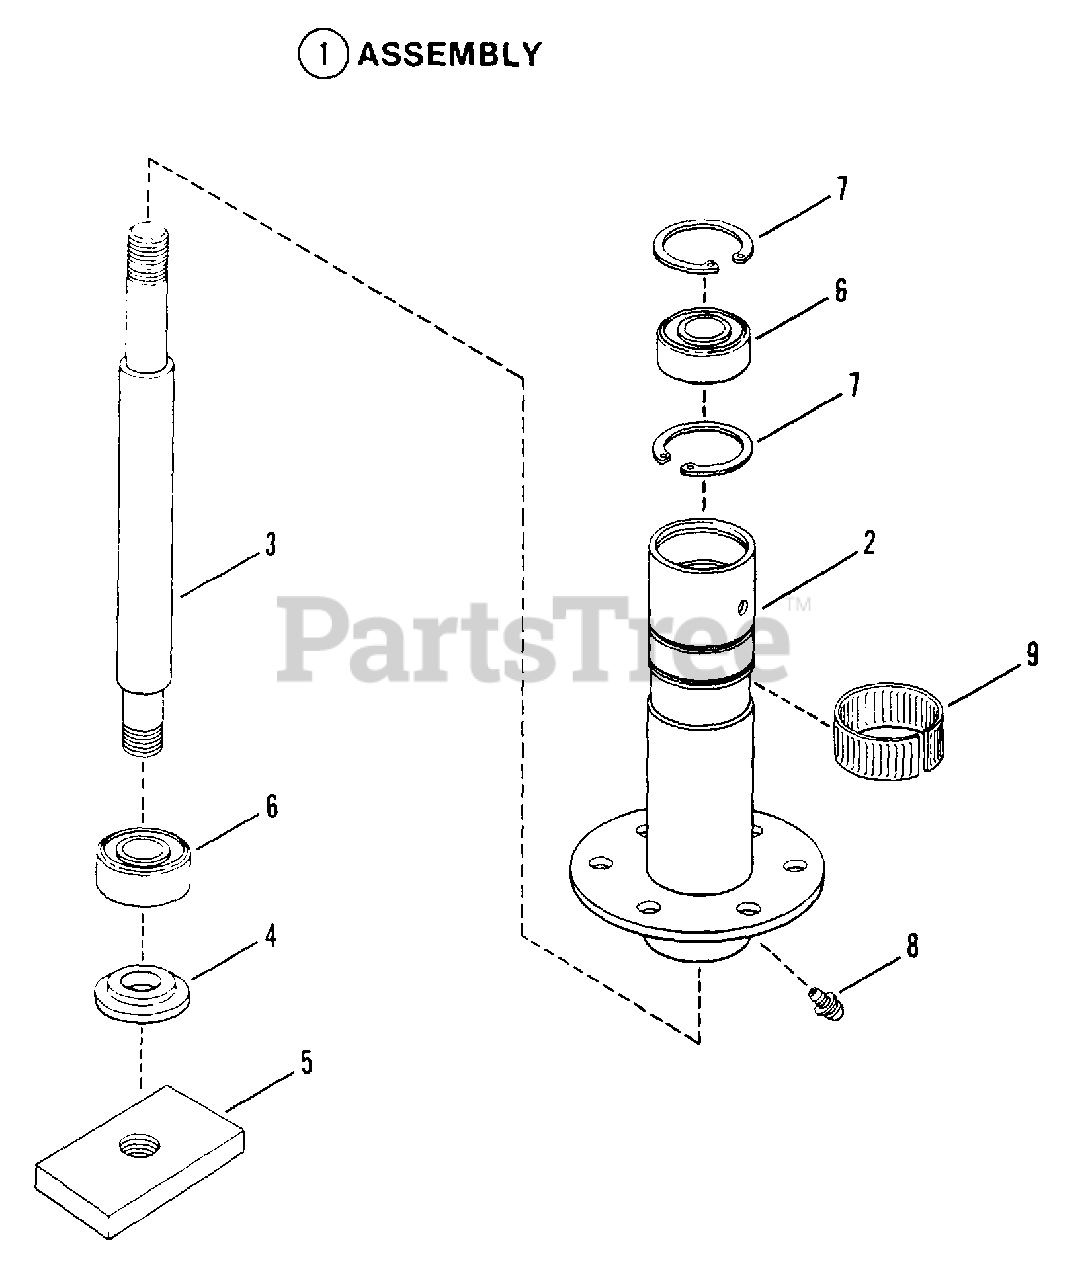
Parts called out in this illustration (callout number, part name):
1	ASSEMBLY, Spindle
2	HOUSING
3	SPINDLE
4	WASHER, Spindle
5	HOLDER, Blade
6	BEARING
7	RING, Retaining
8	FITTING, Lube (Press fit for .187 hole-no ball)
9	RING, Tolerance
